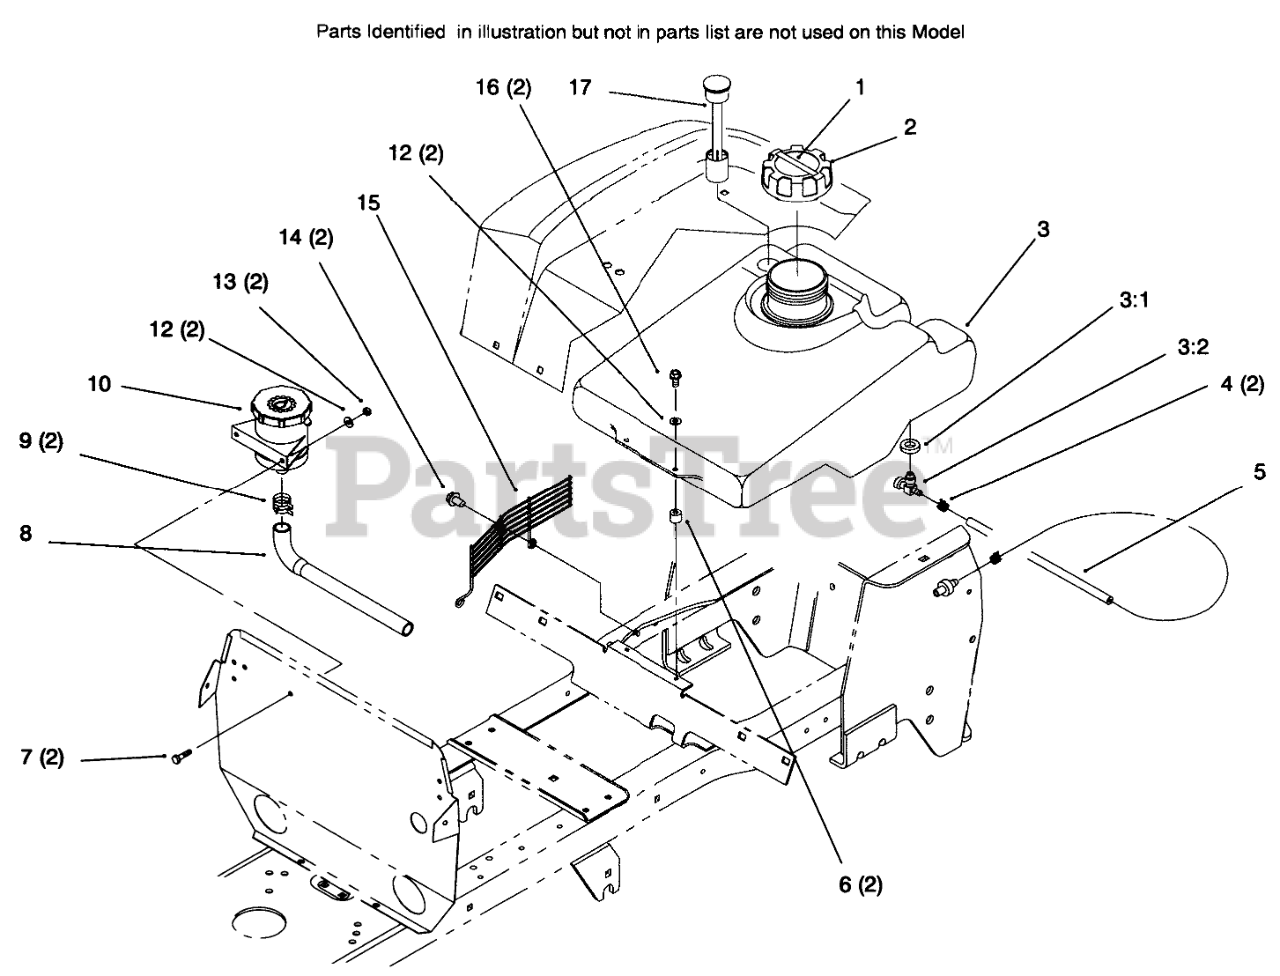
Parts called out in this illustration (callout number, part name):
1	Decal-Oil Check (Only On: 72104)
2	GAS CAP ASM
3	TANK-GAS
3:1	BUSHING
3:2	VALVE-FUEL
4	CLAMP-HOSE
5	HOSE - FUEL LINE TWIN
6	SPACER - FUEL TANK
7	SCREW-HH
8	HOSE - HYDRO
9	CLAMP-HOSE
10	ASS'Y-RESERVOIR
12	WASHER-FLAT
13	NUT-LOCK, NI
14	Screw-HH (Only On: 72104)
15	Guard-Fan (Only On: 72104)
16	SCREW-HH
